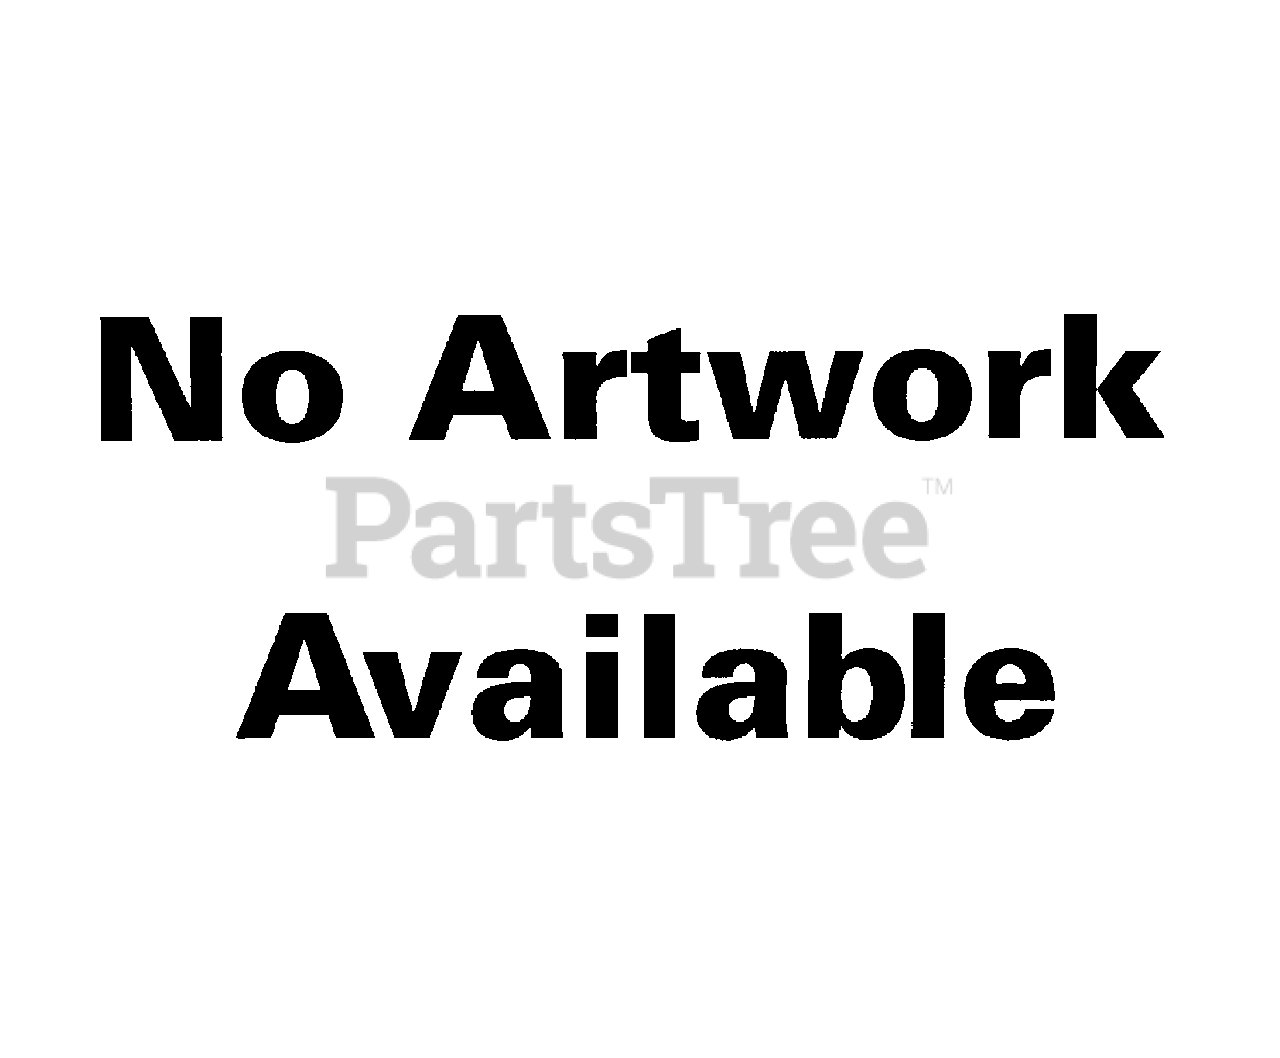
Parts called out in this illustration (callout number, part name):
2	FRAME, MOUNTING (L)
3	RUBBER, MOUNTING (UPPER)
4	RUBBER, MOUNTING (LOWER)
5	COVER, MOUTING RUBBER (UPPER)
6	CASE, SWIVEL *NH282MU* (L) (OYSTER SILVER METALLIC-U)
7	LINER, SWIVEL CASE
8	BLOCK, FRICTION
9	BUSH, SWIVEL CASE
10	COLLAR, SWIVEL CASE
11	PLATE, FRICTION
12	LEVER, FRICTION
13	HOOK, REVERSE LOCK
14	SPRING, REVERSE LOCK
15	SPRING, TILT LEVER
16	SPRING, TILT LINK
17	LEVER, TILT
18	ARM, REVERSE LOCK
19	ROD, RELEASE SWIVEL CASE
20	ARM, TILT
21	BUSH, TILT LEVER
22	BUSH, TILT LEVER
23	SHAFT, TILT
24	BRACKET, TILT SHAFT
25	BRACKET, RELEASE ROD
26	BRACKET, TILT LEVER
27	SHAFT, REVERSE LOCK (A)
28	SHAFT, REVERSE LOCK (B)
29	COLLAR, REVERSE LOCK
31	BOLT, FLANGE (6X12)
33	BOLT, FLANGE (10X25)
34	BOLT, FLANGE (8X45)
36	BOLT, STUD (8X26)
38	NUT, SELF-LOCK (8MM)
40	WASHER, THRUST
41	WASHER, PLAIN (6MM)
42	WASHER, LOCK
44	WASHER (8MM)
45	WASHER, NYLON (8MM)
46	PIN, SPRING (3.0X22)
47	PIN, SPRING (3.0X25)
48	PIN, SPLIT (2.0)
49	NIPPLE, GREASE
50	O-RING (34X2.4)
52	NUT, HEX. (6MM)
53	BOLT, FLANGE (6X12)
